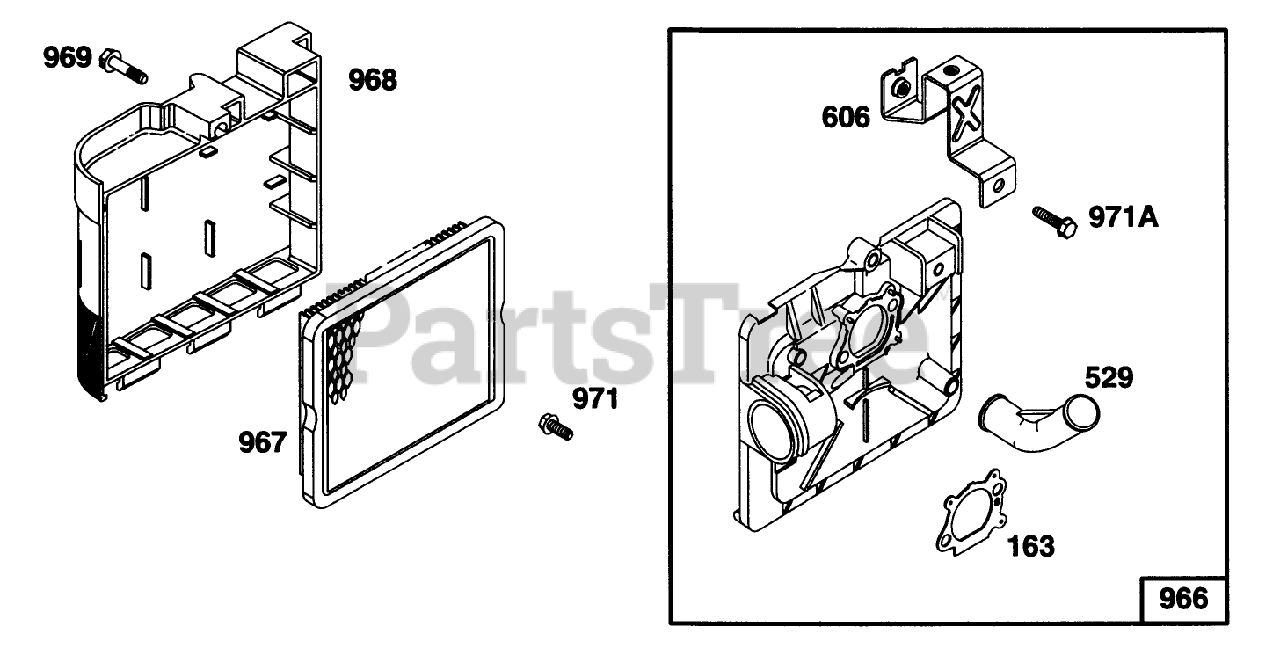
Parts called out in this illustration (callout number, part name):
163	Gasket-Cleaner, Air
529	Grommet
606	Strap-Bracket
966	Base-Primer, Air Cleaner
967	Filter-Air Cleaner, Cartridge
968	Air Cleaner Cover
969	Screw-Cover Mt.
971	Screw-Air Cleaner
971A	Screw-Hex.
